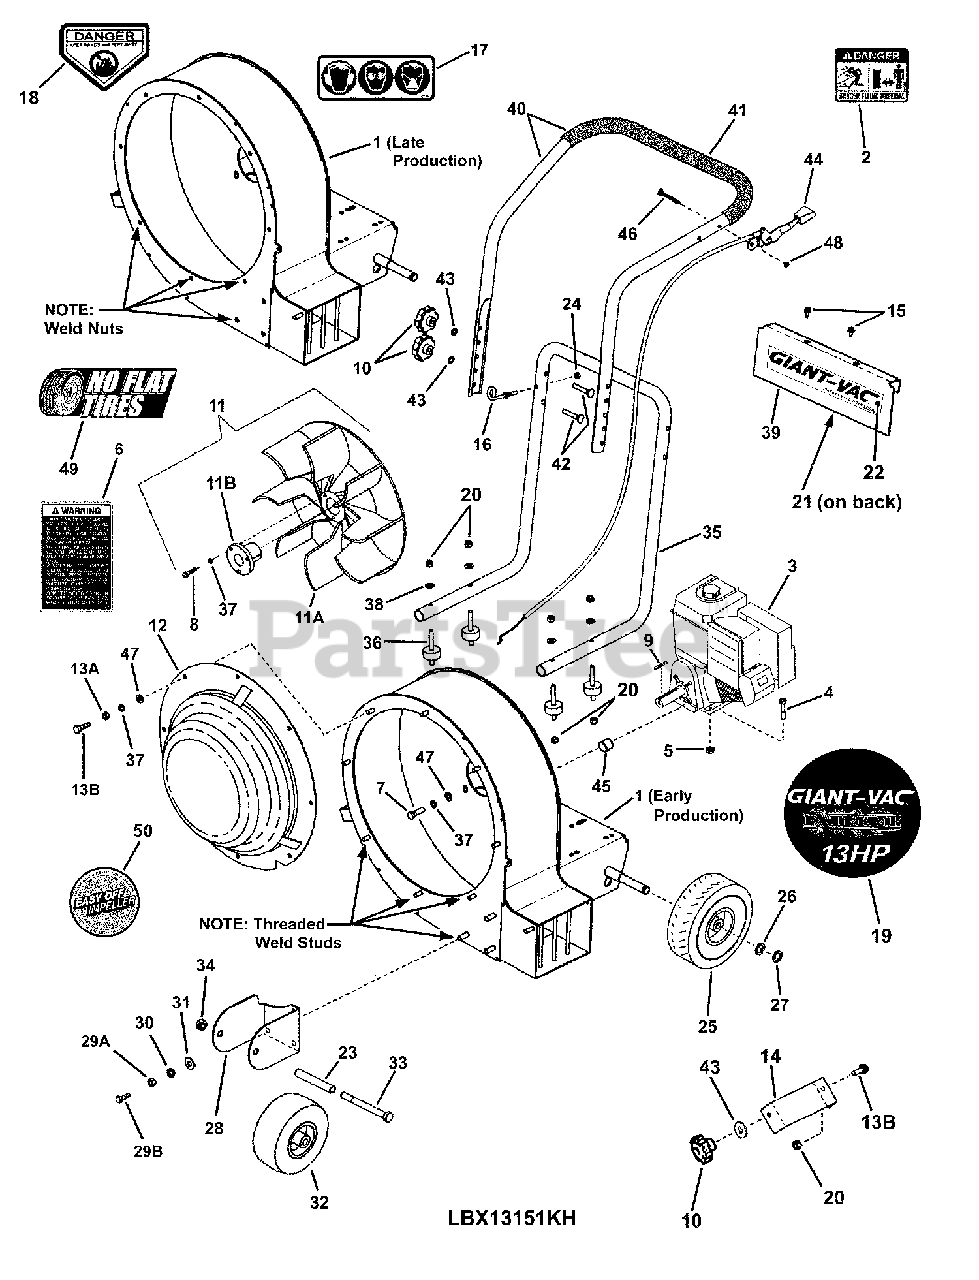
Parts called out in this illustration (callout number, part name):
1	WELDMENT, Housing - Extreme Blower
2	DECAL, Thrown Objects, Large
3	* ENGINE, Kohler 13HP, Model CS12T
4	SCREW, 5/16-18 x 1-1/2 Hex Head Cap, GR 5
5	NUT, 5/16-18 Hex Flange Lock, GR 5
6	DECAL, Warning - Leaf Blower
7	SCREW, 5/16-24 x 1-3/4" Hex Head Cap, GR 5
8	SCREW, 5/16-18 x 1-1/4", Hex Head Cap, GR 5
9	KEY, 1/4" Square x 2"
10	KNOB, Fluted (5/16-18 thread)
11	ASSEMBLY, 15" 9 Blade Impeller
11A	IMPELLER, Cast, 15" O.D.
11B	HUB, Taper-Lok, Type 1 - P1 x 1.000
12	WELDMENT, Intake Baffle - Extreme
13A	NUT, 5/16-18 Hex, GR 5 or B
13B	SCREW, 5/16-18 x 3/4" Hex Head Cap, GR 5
14	DEFLECTOR, Side Air
15	SCREW, 5/16-18 x 5/8" Hex Washer Self-Tap
16	GUIDE, Rope (1/4-20 thread)
17	DECAL, Personal Protection
18	DECAL, Danger, Cut Finger
19	DECAL, 13HP Extreme
20	NUT, 5/16-18 Hex Nyloc
21	DECAL, GIANT-VAC (Small)
22	DECAL, GIANT VAC
23	TUBE, Front Wheel - Extreme
24	NUT, 1/4-20 Hex Center Lock, GR 5 or B
25	ASSY., Wheel & Tire 4.10/3.50-4 "Flatfree"
26	WASHER, .64 x .99 x .05 Flat
27	RING, External Retaining
28	BRACKET, Front Wheel Mounting
29A	NUT, 3/8-16 Hex, GR 5 or B
29B	SCREW, 3/8-16 x 1" Hex Head Cap, GR 5
30	WASHER, 3/8" Split Lock
31	WASHER, 3/8" Flat
32	ASSY., Tire & Wheel 9 x 3.50-4 "Flatfree"
33	BOLT, 1/2-13 x 5" Hex Head Cap
34	NUT, 1/2-13 Hex Center Lock, GR 5
35	HANDLE, Lower Folding - Wide - Blower
36	MOUNT, Vibration (5/16-18, both ends)
37	WASHER, 5/16" Split Lock
38	WASHER, 5/16" Curved
39	DASH PANEL, Blower - Wide
40	ASSY, Upper Handle & Grip - Wide
41	GRIP, 1.0 x 21-1/2" Foam
42	BOLT, 5/16-18 x 2", Curved Hd. Sq. Neck
43	WASHER, 5/16" Internal Tooth Lock
44	THROTTLE CONTROL, Kohler (35.24/3)
45	SPACER, .375 I.D. x .750 O.D. x .5
45	SPACER, .375 I.D. x .750 O.D. x .750
46	SCREW, 1/4-20 x 2" Hex Head Cap, GR 5
47	WASHER, .34 x .69 x .08 Flat
48	NUT,1/4-20 Hex Nyloc
49	DECAL, No Flat Tire
50	DECAL, Easy Off Impeller
